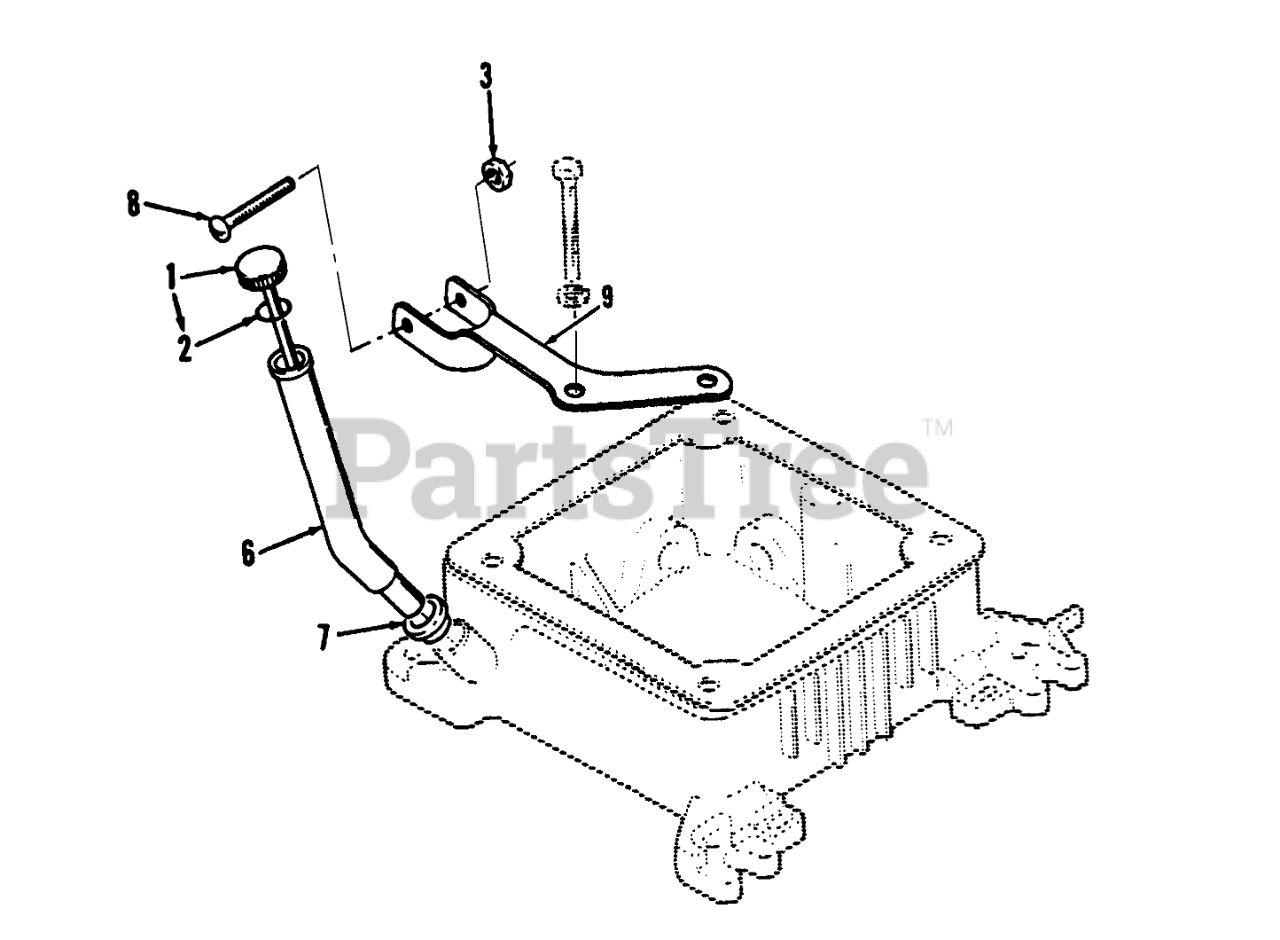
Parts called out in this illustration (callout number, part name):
1	Cap & Indicator-Oil Fill (Includes O-Ring) Dipstick-1.75 Quart Capacity Specifies Pints-16.27" Long
2	O-Ring
3	NUT - SPEED
6	Tube-Oil Fill
7	Seal
8	SCREW - PAN HEAD
9	BRACKET-FILL TUBE
